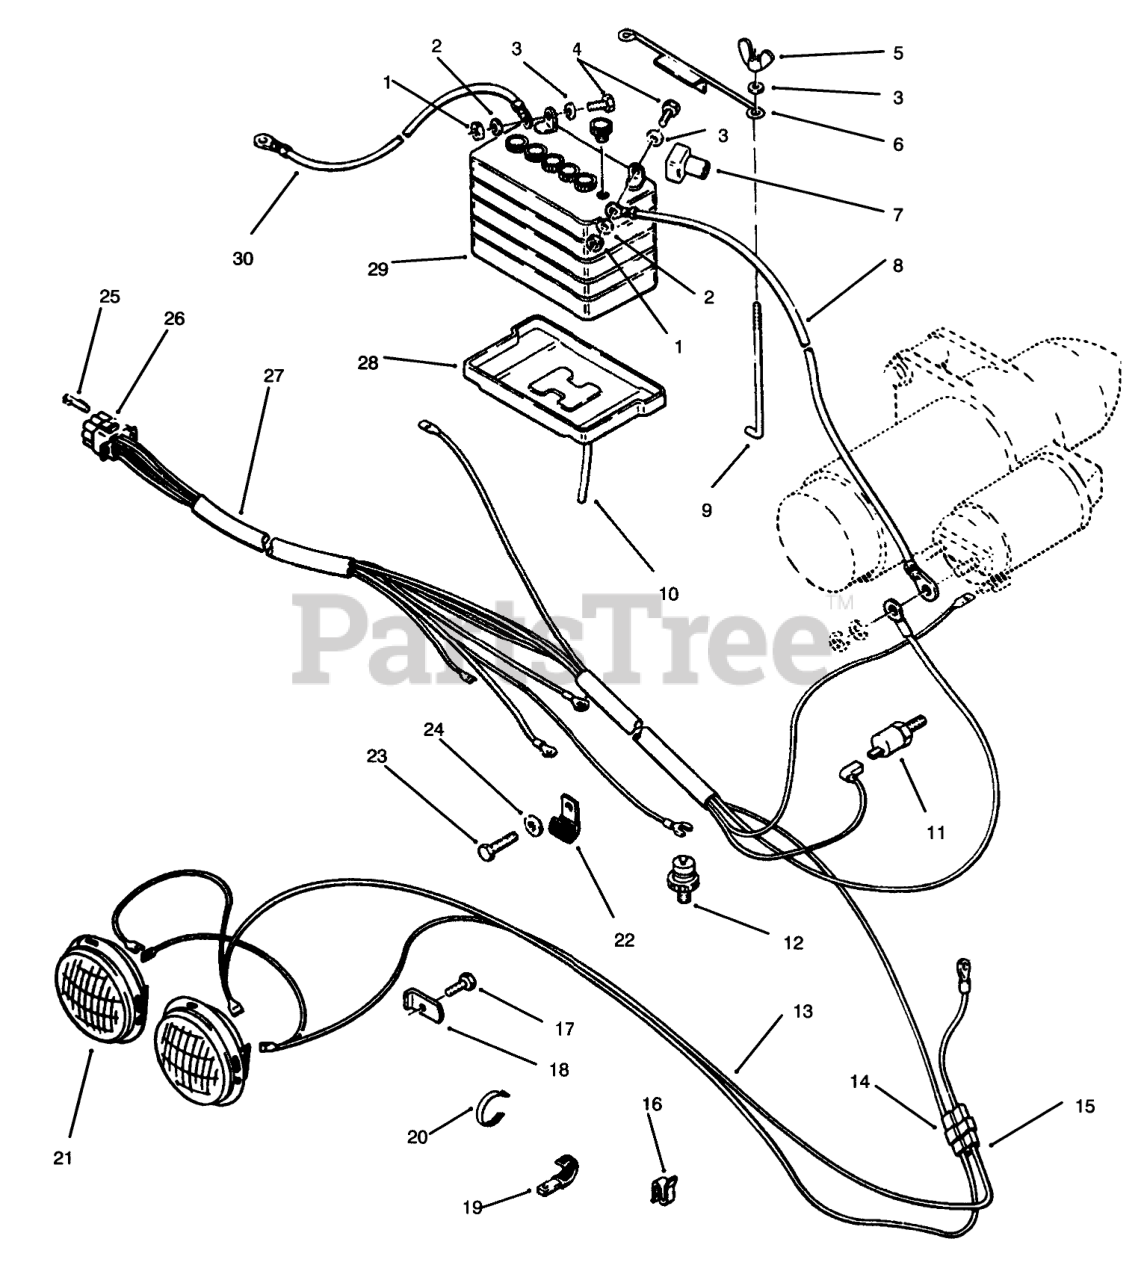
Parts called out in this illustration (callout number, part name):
1	NUT-LOCK, NI
2	WASHER-LOCK
3	WASHER-FLAT
4	SCREW-HH
5	NUT-WING
6	HOLDDOWN-BATTERY
7	Boot
8	ASS'Y-WIRE
9	HOOK-BATTERY RETAIN
10	TUBE-21" BATTERY DRAIN
11	HIGH TEMPERATURE
12	SWITCH
13	HARNESS-HEADLIGHT
14	MALE CONNECTOR
15	CONNECTOR BODY
16	SPEED CLIP
17	SCREW-HWH
18	LOCK-HEADLIGHT
19	CLIP
20	PLASTIC TIE
21	HEADLAMP
22	CLIP-WIRE
23	SCREW-HWH
24	LOCKWASHER 1/4 IT
25	CONTACT SOCKET
26	CONNECTOR CAP
27	WIRING HARNESS
28	TRAY-BATTERY
29	Battery
30	ASS'Y-WIRE
